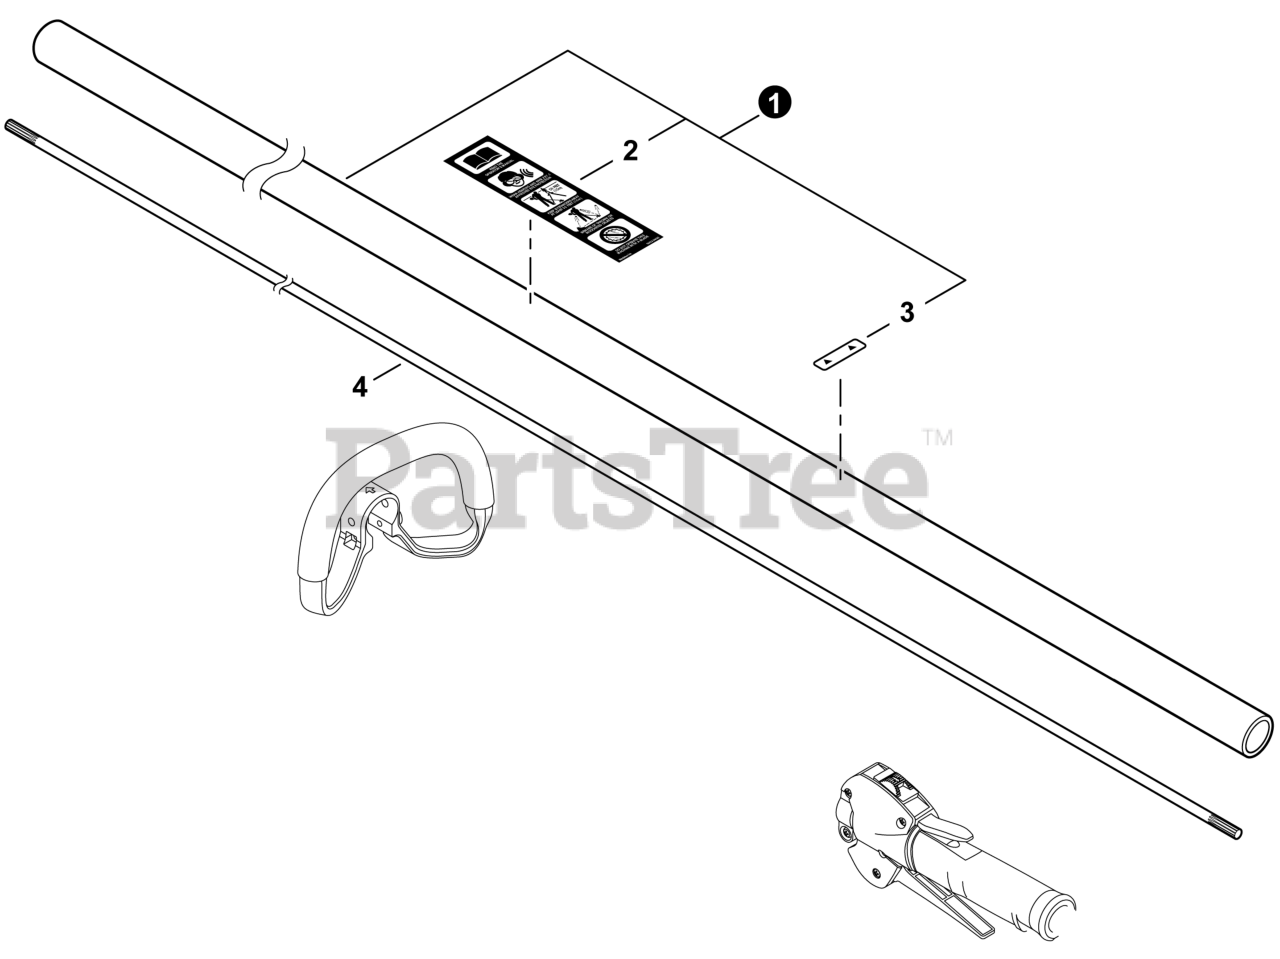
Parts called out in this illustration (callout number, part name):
1	MAIN PIPE ASSY
2	LABEL - CAUTION
3	LABEL - ALIGNMENT
4	DRIVESHAFT
